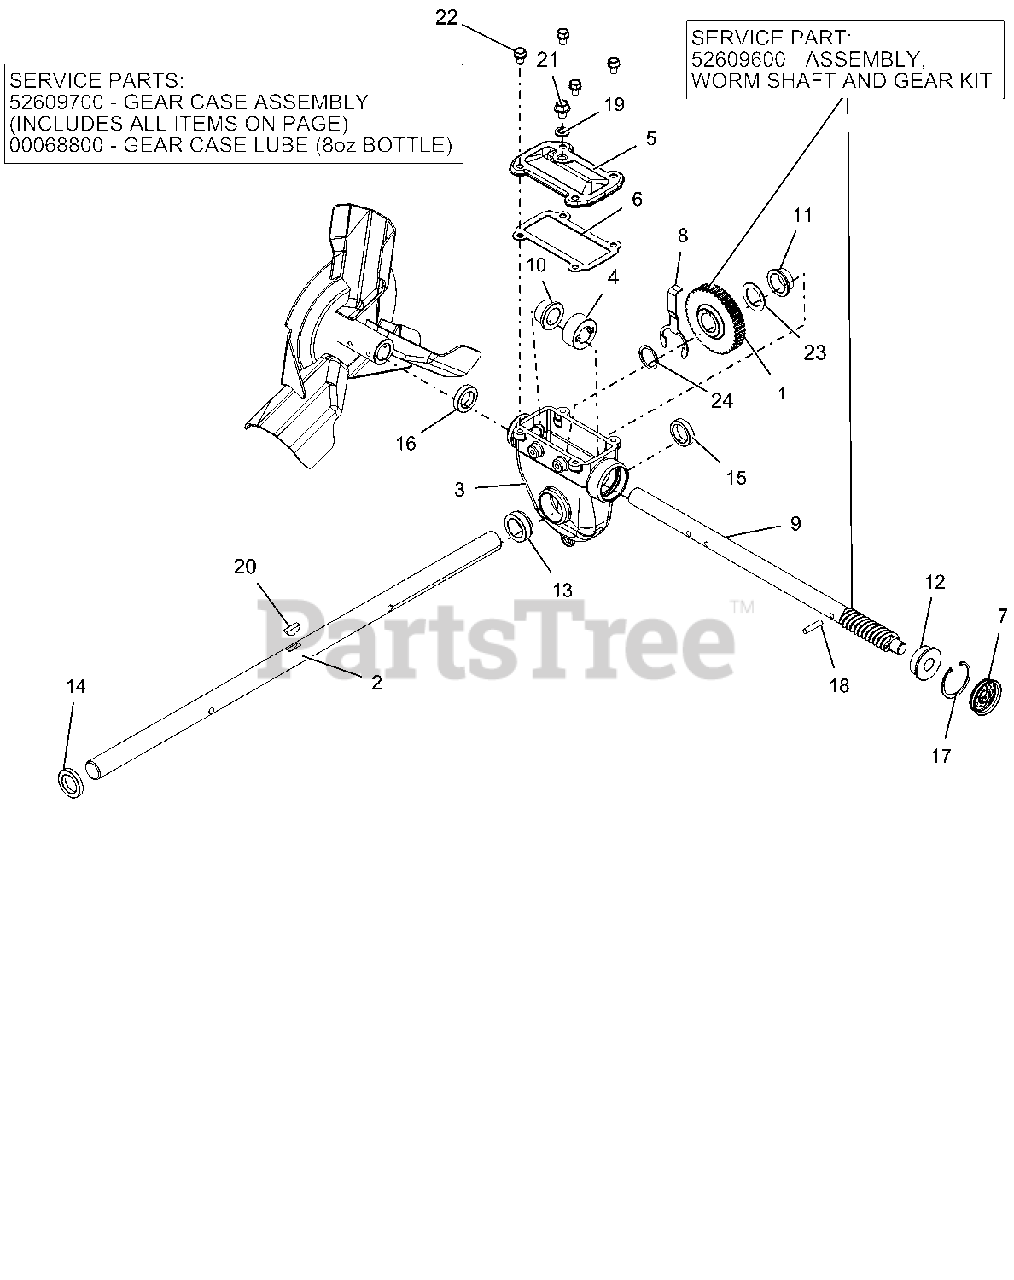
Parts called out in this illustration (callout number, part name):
1	WORM GEAR
2	SHAFT, RAKE-28"
3	GEARCASE, LARGE MACHINED
4	THRUST COLLAR, .875"ID SLIPFIT
5	COVER, TOP - LARGE IRON
6	GASKET, TOP - LARGE GEARCASE
7	COVER, GEAR CASE 1.75"
8	BUSHING RETAINER, LARGE
9	ASSY, WORM SHAFT & GEAR
9	SHAFT, WORM - PRO
10	BSHG-FLG .879X1.128X.75X1.45
11	BSHG-FLG 1.006X1.128X.555X1.45
12	BSHG-FLG .628X1.503X.58X1.725
13	BSHG-FLG LARGE, RIGHT
14	SEAL-OIL .999X1.500X.250 TBC29
15	SEAL-OIL .999X1.375X.312 TBC29
16	SEAL-OIL .873X1.375X.312 TBC29
17	RG-RTNG-INT 1.750X.062
18	PIN-STR .250X1.12 6150
19	WSHR-BND-SEAL .38X.75X.11 GALV
20	KEY-WDRF .25X.875 HRD #A
21	@SCR-ROLOK .38-16X.50 HWH YWZC
22	BOLT, SEMS .31-18X.50 GR5 YWZC
23	WSHR-FL-STL 1.010X1.505X.062YZ
24	WSHR-FL-STL 1.010X1.250X.068YZ
25	GEAR CASE, 28" IRON PRO TOP-LD
26	ARIENS L3 LUBE, 8 OZ BOTTLE
